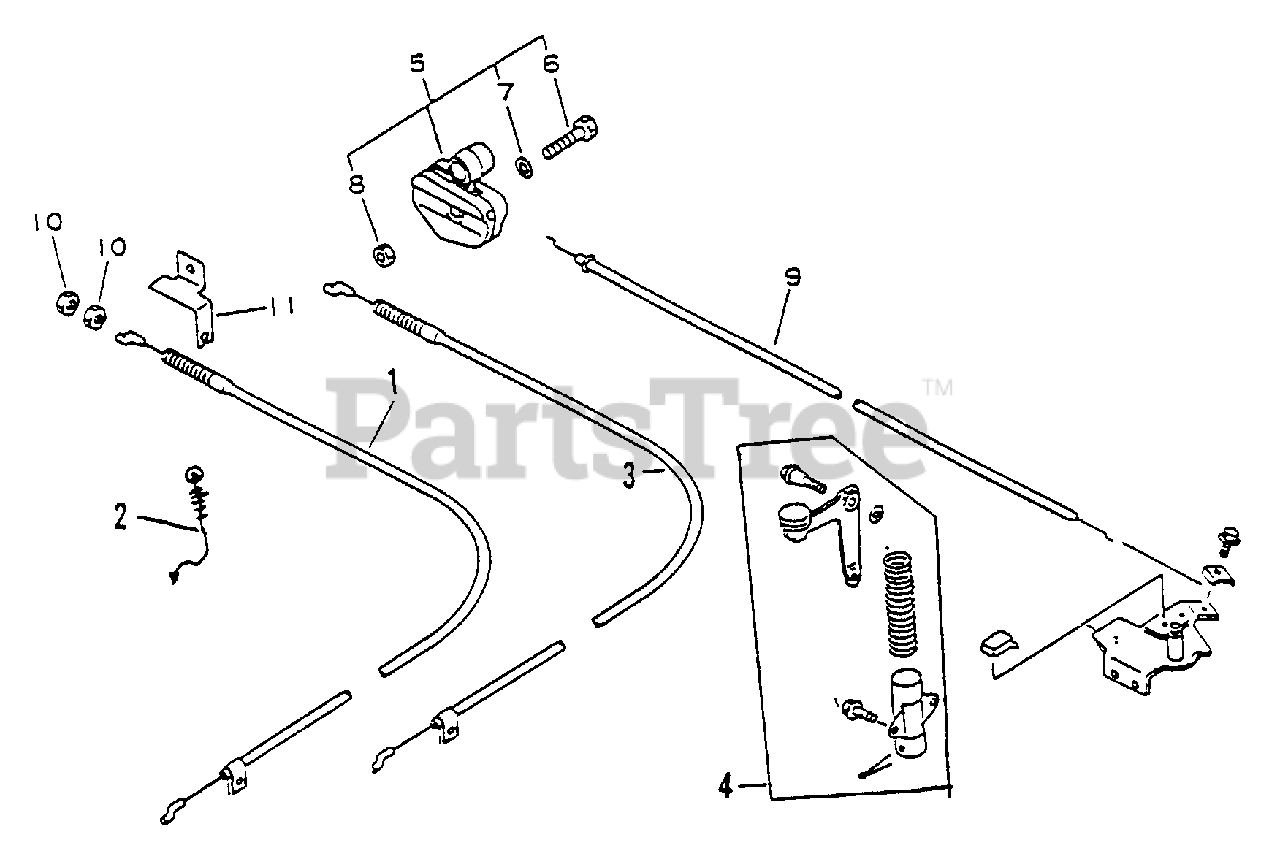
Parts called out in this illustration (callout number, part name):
1	WIRE, BRAKE
2	CLIP
3	WIRE, BRAKE
4	CHAIN BRAKE ASSY
5	LEVER, THROTTLE
6	BOLT - 1/4 X 1-3/4"
7	WASHER - 1/8" -- STAR
8	NUT - 1/4-20
9	WIRE KIT, BRAKE
10	NUT - 5/16-18
11	BRACKET, BRAKE WIRE
